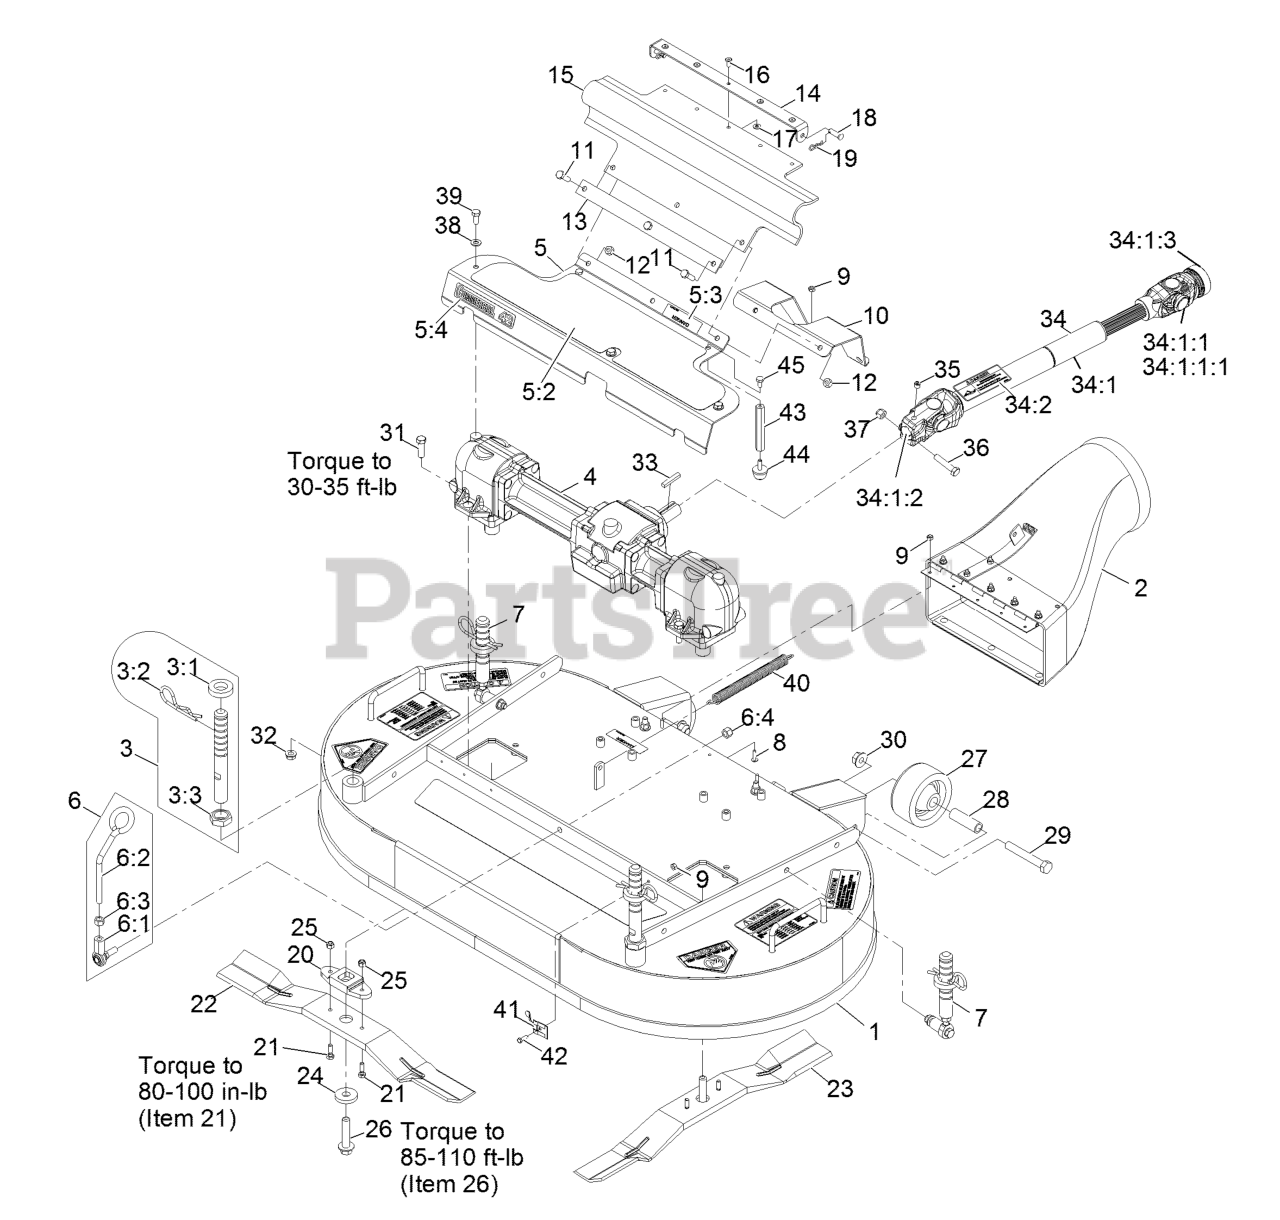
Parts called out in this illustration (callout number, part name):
1	DECK ASM
2	DISCHARGE TUBE ASM
3	FRONT DECK HEIGHT ADJUST
3:1	SPACER-DECK SUPPORT
3:2	PIN-CUT HEIGHT
3:3	NUT-JAM
4	GEARBOX ASM
5	ASM,GEARBOX COVER 42 W/DE
5:2	PAD-ANTI SKID
5:3	DECAL-COVER, MISSING
5:4	DECAL,COMMERCIAL 42
6	DECK LATCH ASM
6:1	BALLJOINT-RH
6:2	LATCH-DECK
6:3	NUT-HEX
6:4	NUT-LOCK
7	REAR DECK HEIGHT ADJUST A
8	SCREW-HEAD, TRUSS
9	NUT-LOCK, NI
10	GUARD-DRIVE SHAFT
11	SCREW-HH
12	NUT-LOCK, NI
13	STRAP-DRIVE, LINE COVER
14	BRACKET-GUARD, PTO
15	GUARD-PTO
16	RIVET-BLIND
17	WASHER-FLAT
18	PIN-CLEVIS
19	PIN-COTTER
20	DRIVER-BLADE
21	BOLT-SHEAR
22	BLADE,22 INCH RH
23	BLADE,22 INCH LH
25	NUT-LOCK, NI
26	BOLT-BLADE
27	ROLLER-DECK
28	SPACER-ROLLER
29	SCREW-HH
30	NUT-HHF
31	SCREW-HH
32	NUT-HHF, WHIZ
33	KEY-SQUARE
34	DRIVE SHAFT ASM
34:1	Shaft,Drive Telescoping
34:1:1	U-JOINT KIT
34:1:1:1	FITTING-GREASE
34:1:2	YOKE-KEYED
34:1:3	YOKE-QUICK DISCONNECT
34:2	DECAL-DRIVELINE
35	SCREW-SET, HSH
36	SCREW-HH
37	NUT-LOCK, NI
38	WASHER-PLAIN
39	SCREW-HH
40	SPRING-EXTENSION
41	CLIP-DECK, HOLD UP ROD
43	STAND-OFF
45	SCREW-HH
